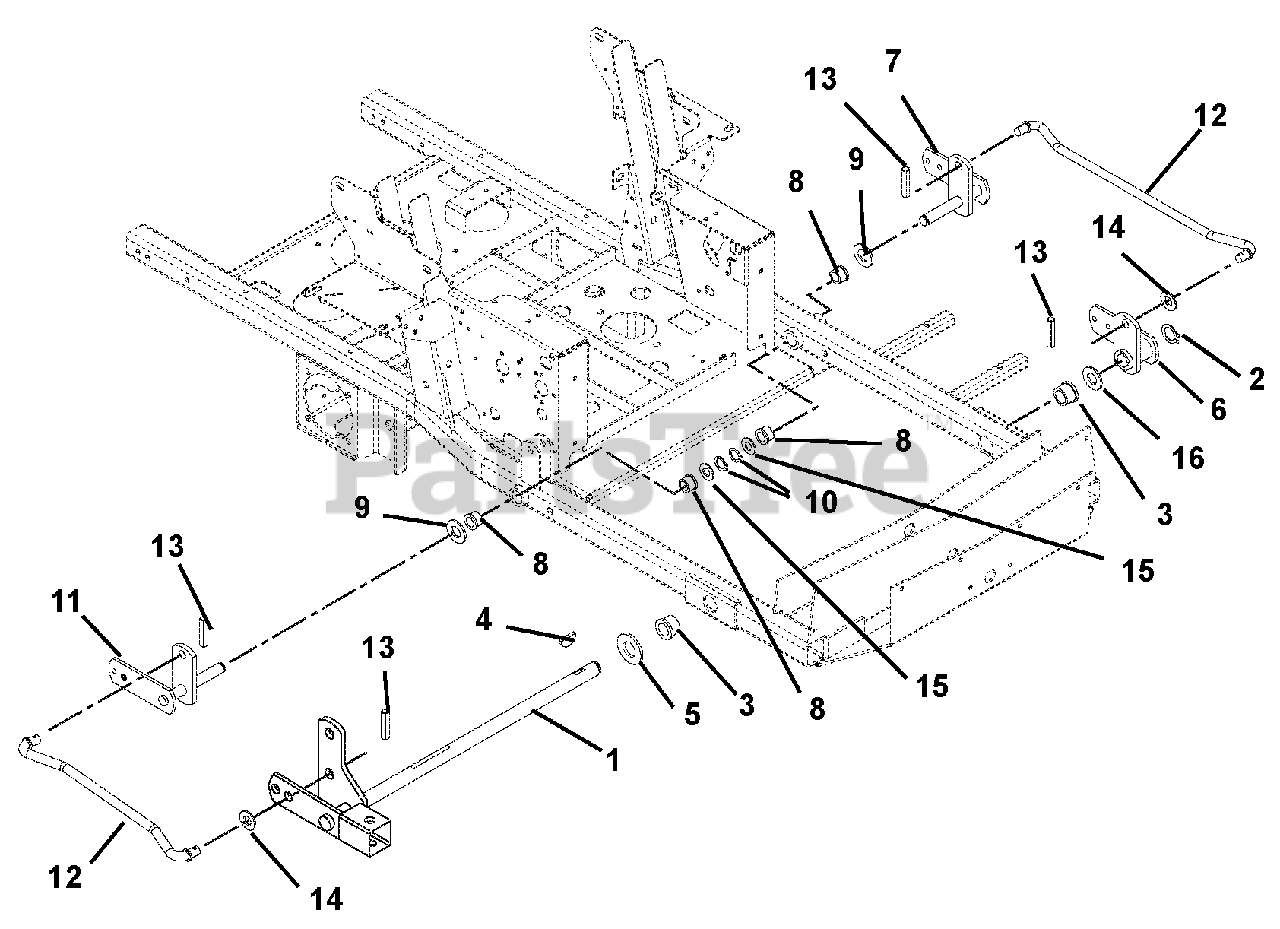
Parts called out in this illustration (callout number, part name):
1	Lift, Mower
2	Ring, Retaining External 1.00 x .078
3	Bushing, Flange Nylon 1.020 x 1.385 x .75 x 1.75
4	Key, Woodruff .25 x 1.00
5	Washer, Flat Steel 1.063 x 2.00 x .134
6	Weldment, Lift Arm Front
7	Weldment, Lift Arm Shaft Left Hand
8	Bushing, Flange Nylon .762 x 1.00 x .58 x 1.48
9	Washer, Hardened Steel .758 x 1.23 x .031
10	Ring, Retaining External .689 x .077
11	Weldment, Lift Arm Shaft Right Hand
12	Rod, Lift Assist
13	Pin-Roll .250 x 1.25 Stainless Steel
14	Washer-Flat-Steel .630 x 1.25 x .062
15	Washer, Flat Steel .755 x 1.25 x .125
16	Washer, Hardened Thrust 1.00 x 1.55 x .03
